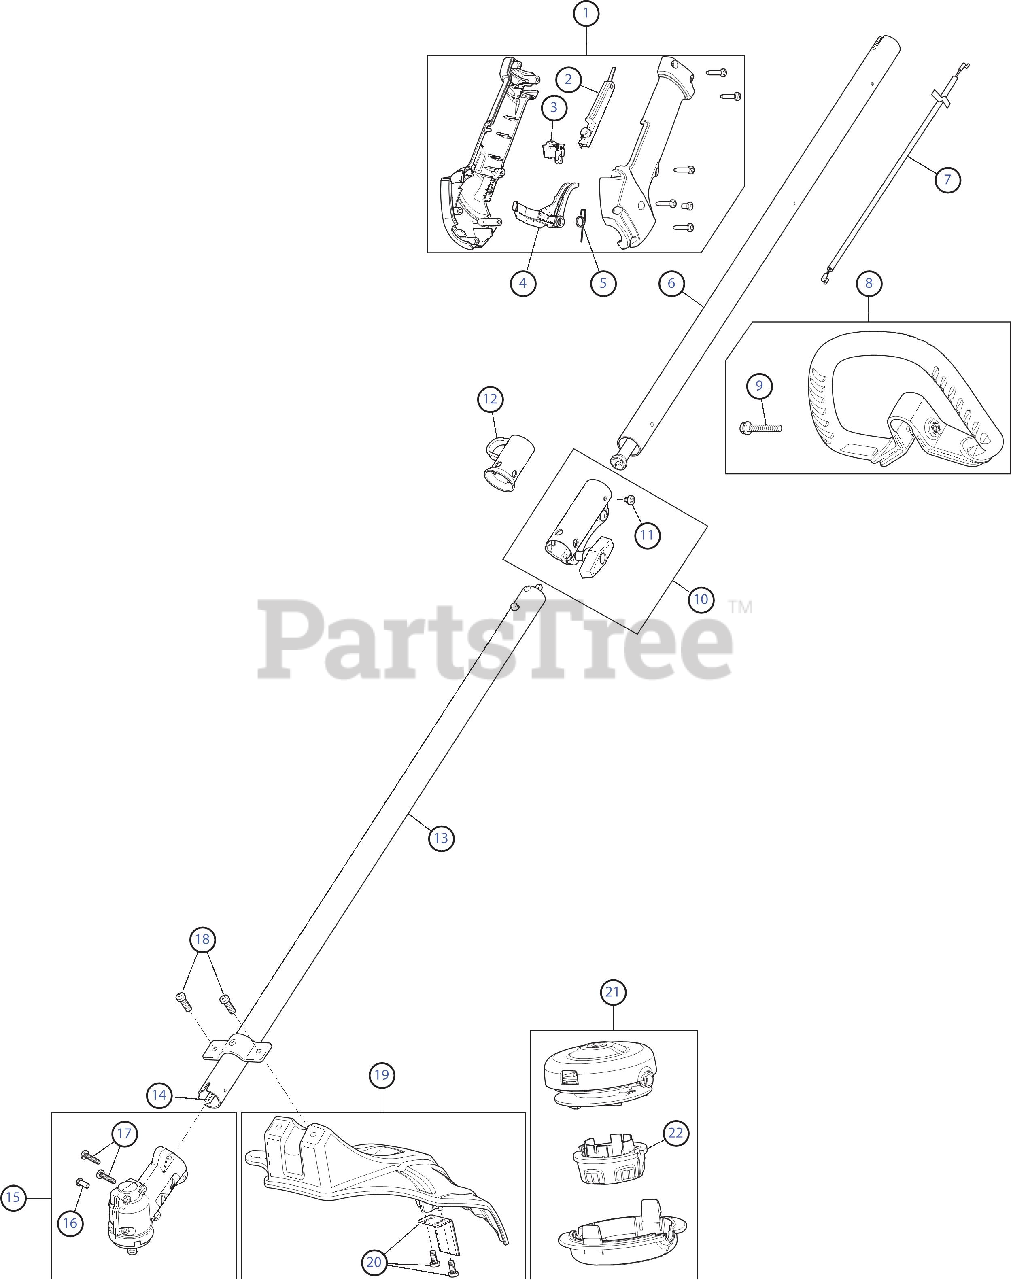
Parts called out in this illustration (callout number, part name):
1	Throttle Housing Assembly
2	Throttle Trigger Lock-Out
3	Throttle Switch Assembly
4	Throttle Trigger
5	Throttle Trigger Spring
6	Upper Drive Shaft Assembly
7	Throttle Cable
8	D-Handle Assembly
10	Split Boom Coupler
11	Coupler Anti-Rotation Screw
12	Hanger
13	Lower Drive Shaft Housing
14	Lower Flexible Drive Shaft
15	Gearbox Assembly
16	Anti-Rotation Screw
17	Gearbox Mounting Hardware
18	Shield Mounting Screws
19	Shield Assembly
20	Blade Assembly
21	Cutting Head Assembly
22	Bump Knob
